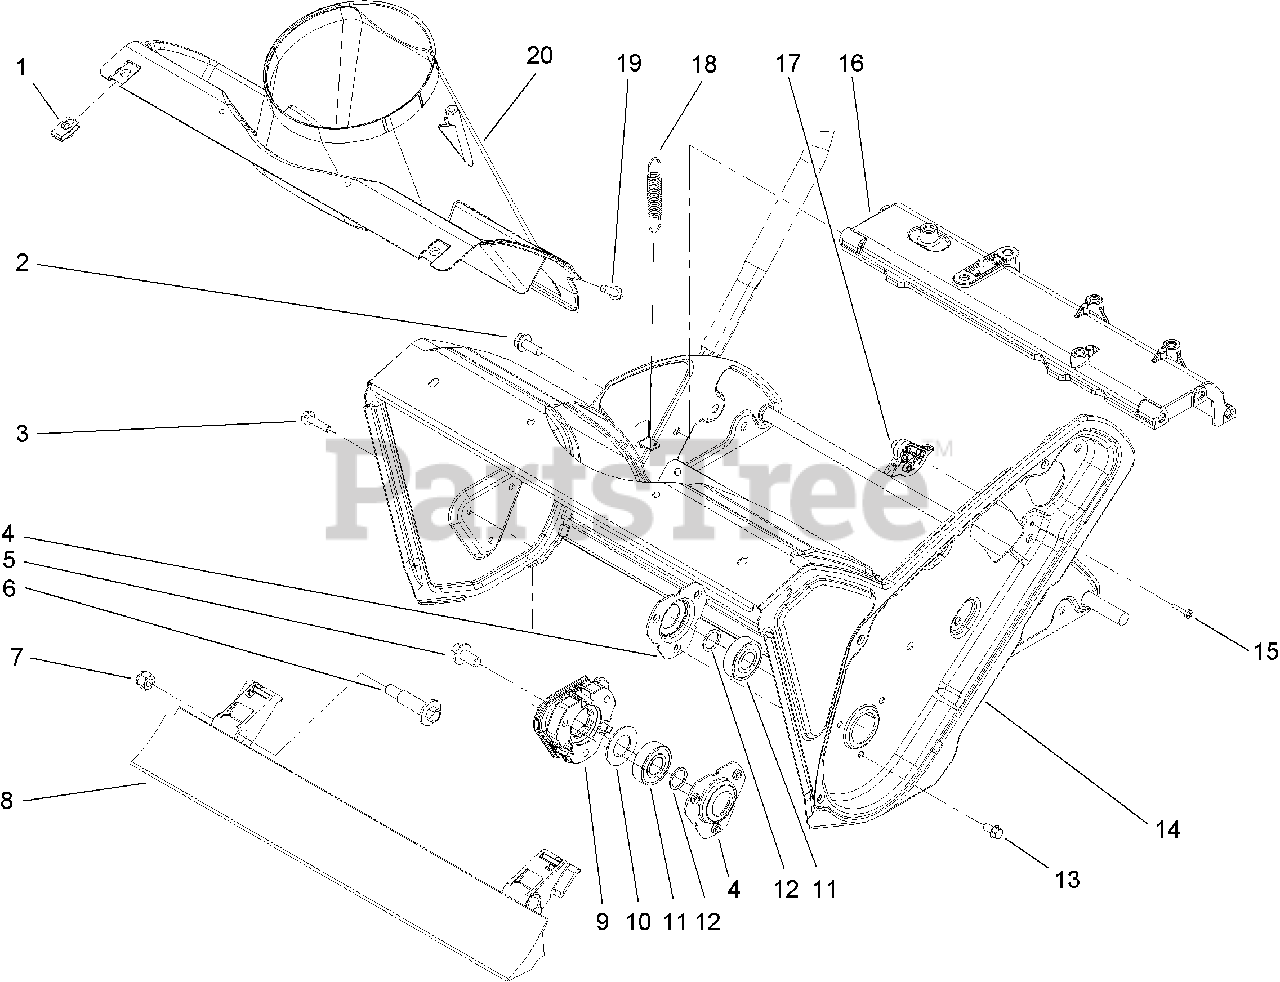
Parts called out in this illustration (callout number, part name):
2	SCREW-HWHTF
3	SCREW-HWHTF
4	FLANGE-BEARING
5	SCREW-HWH
6	BOLT-WHEEL
7	NUT-LOCK, NI
8	BLADE-SCRAPER
9	SPACER-BEARING, RH
10	WASHER-RUBBER
11	BEARING-BALL
12	WASHER-THRUST
13	SCREW-HWH
14	HOUSING-AUGER
15	SCREW-PPH
16	BRACE-FRAME
17	GUIDE-CABLE, CLUTCH
18	SPRING-EXTENSION
19	SCREW-HWH
20	CHUTE-LOWER
